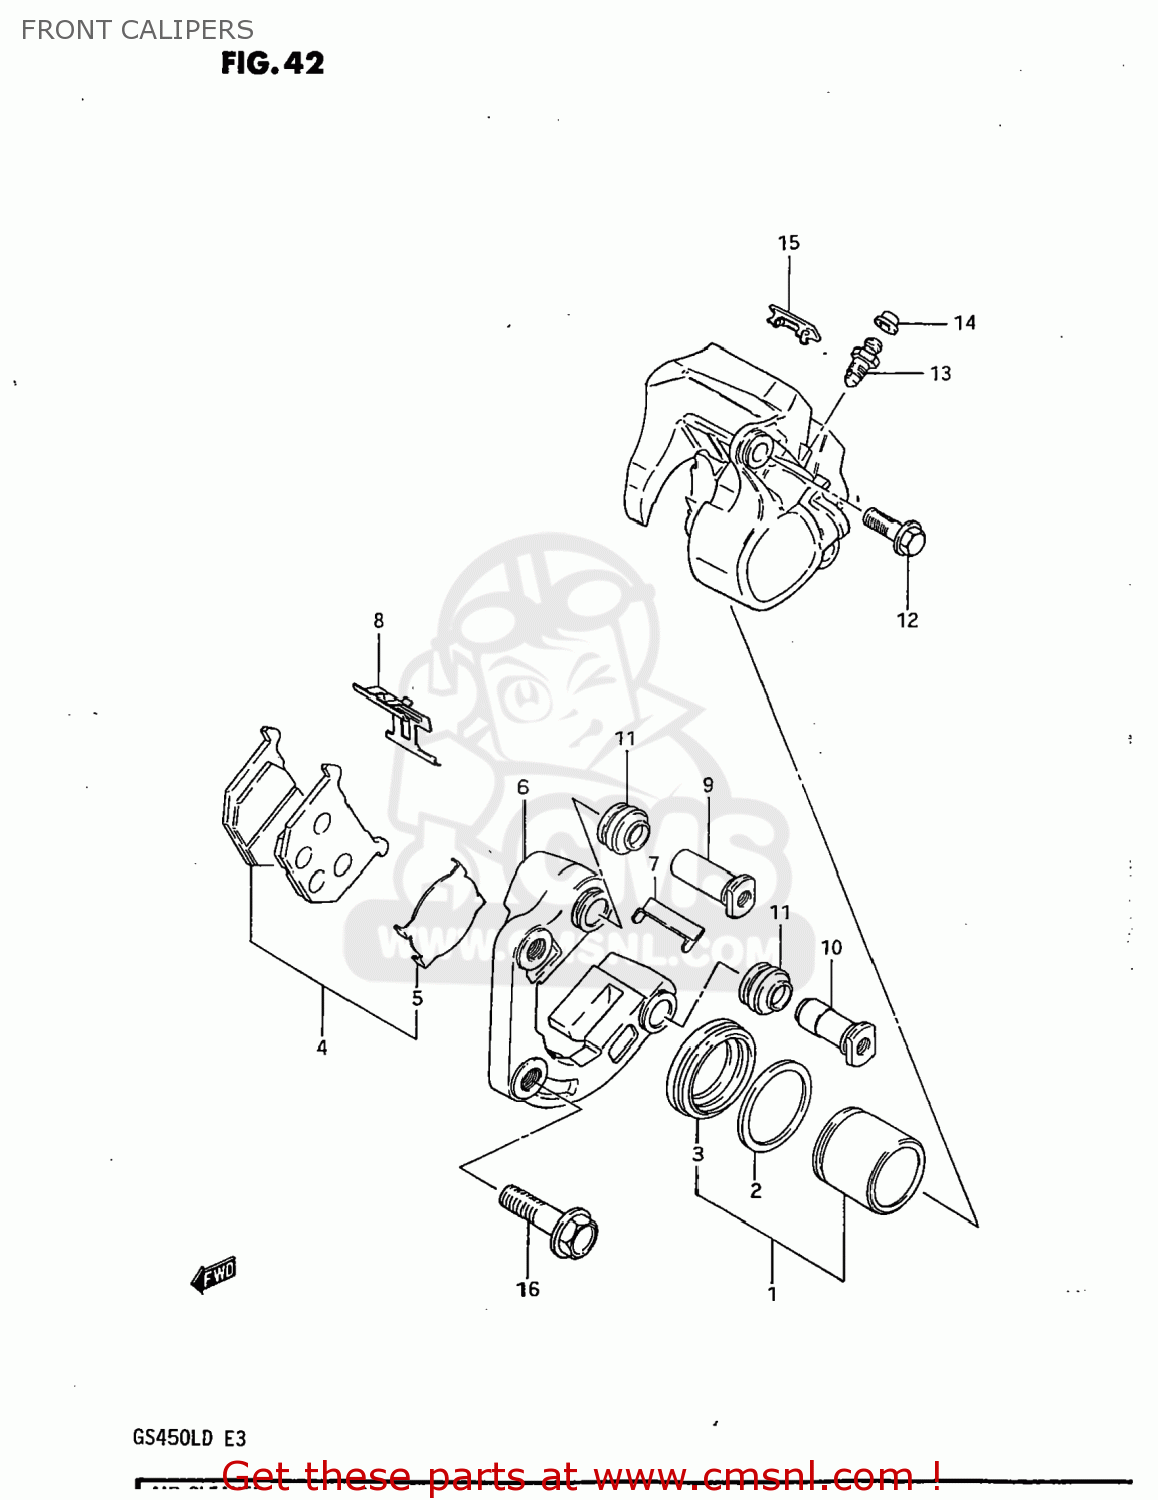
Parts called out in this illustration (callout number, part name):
1	PISTON SET
2	SEAL,FR CALIPE
3	BOOT,PISTON
4	PAD SET,BRAKE (MCA)
5	SHIM,PAD
6	CARRIER,CALIPER,LEFT
7	GUIDE,PAD
8	SPRING,PAD
9	AXLE NO.1
10	AXLE NO.2
11	BOOT,AXLE
12	BOLT
13	BLEEDER
14	CAP,BREATHER
15	COVER
16	BOLT(10X37)
